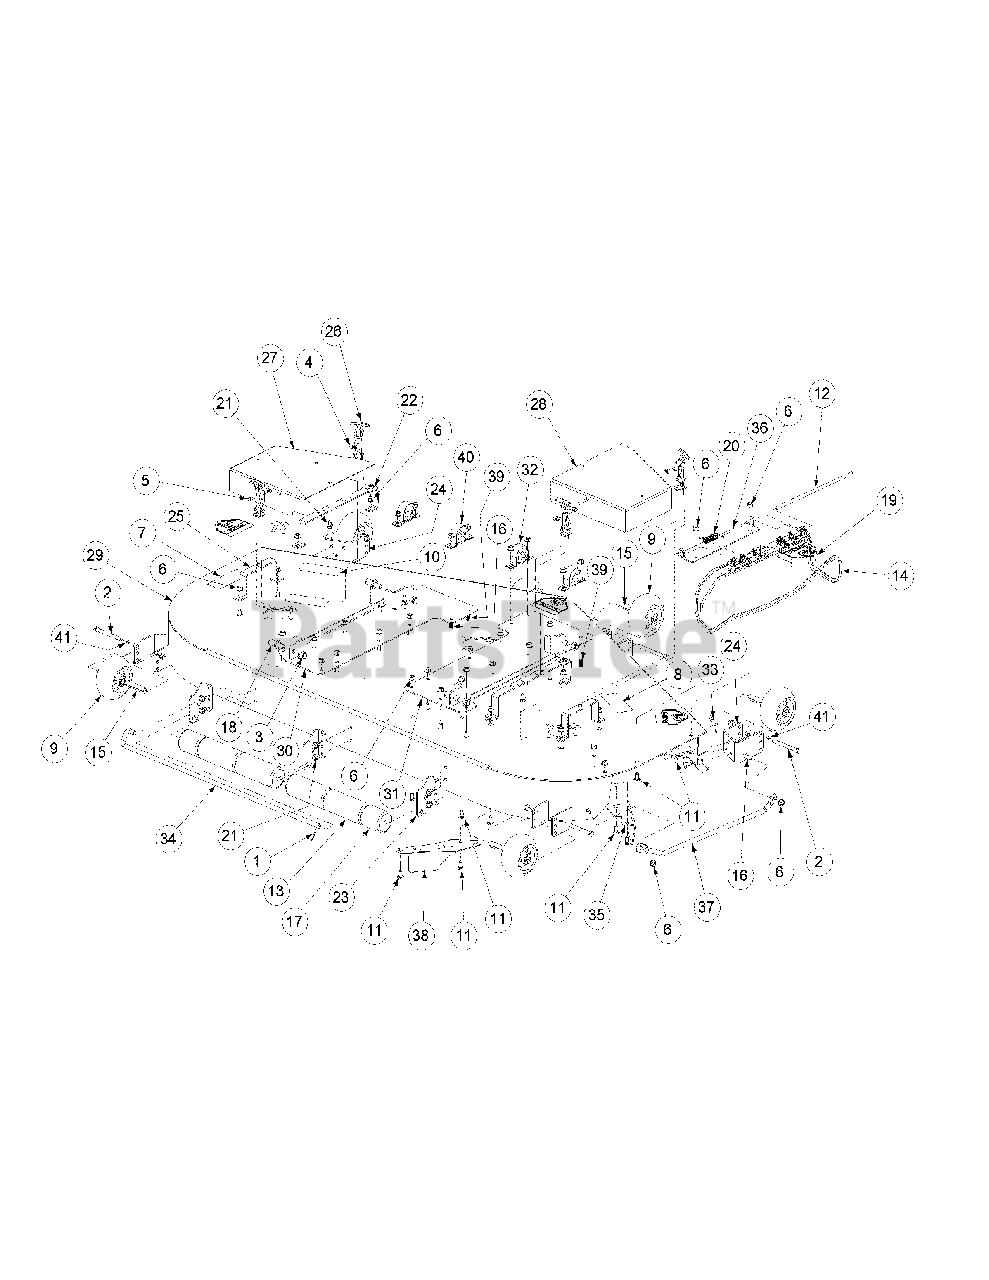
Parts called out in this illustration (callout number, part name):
1	Cotter Pin, .125 Dia. x 1.0
2	Hex Cap Screw, 3/8-16, 3.75
3	Lock Nut, Nylon Insert, 1/2-13
4	Lock Nut, Nylon Insert, #10-32
5	Phillips Head Screw, #10-32 x 1/2
6	Flange Lock Hex Nut, 3/8-16
7	Decal, Rotating Blade
8	Decal, Warning Shield Missing
9	Complete Wheel, 5.00 Dia.
10	Command Cut Large
11	Carriage Bolt, 3/8-16 x .75 Lg.
12	Pin, .375 x 14.06
13	Front Roller
14	Chute Deflector
15	Wheel Spacer
16	Carriage Bolt, 3/8-16 x 1
17	Grass Catcher Roller
18	Pin, 5/8 Dia. x 1.2 Lg.
19	Decal, Danger Hand and Feet
20	Torsion Spring, 0.4ID x 2.16Lg
21	Hex Index Washer Screw, 3/8-16, .5
22	Belt Cover Support
23	Deck Roller Mount Bracket
24	Anti-Scalp Wheel Front Mount Bracket
25	Outer Belt Cover Support Assembly
26	T-Handle Latch Draw
27	Left Hand Deck Belt Cover
28	Right Hand Deck Belt Cover
29	72 Deck Assembly
30	Left Hand Deck Weldment Bracket
31	Right Hand Deck Weldment Bracket
32	Pillow Block, Steel
33	Decal, 72"
34	Roller Pin
35	Chute Bracket
36	Chute Bracket
37	Finger Guard
38	Discharge Baffle Weldment
39	Carriage Screw, 3/8-16 x 1.25
40	Pillow Block, Bronze
41	Flat Washer, 3/8
